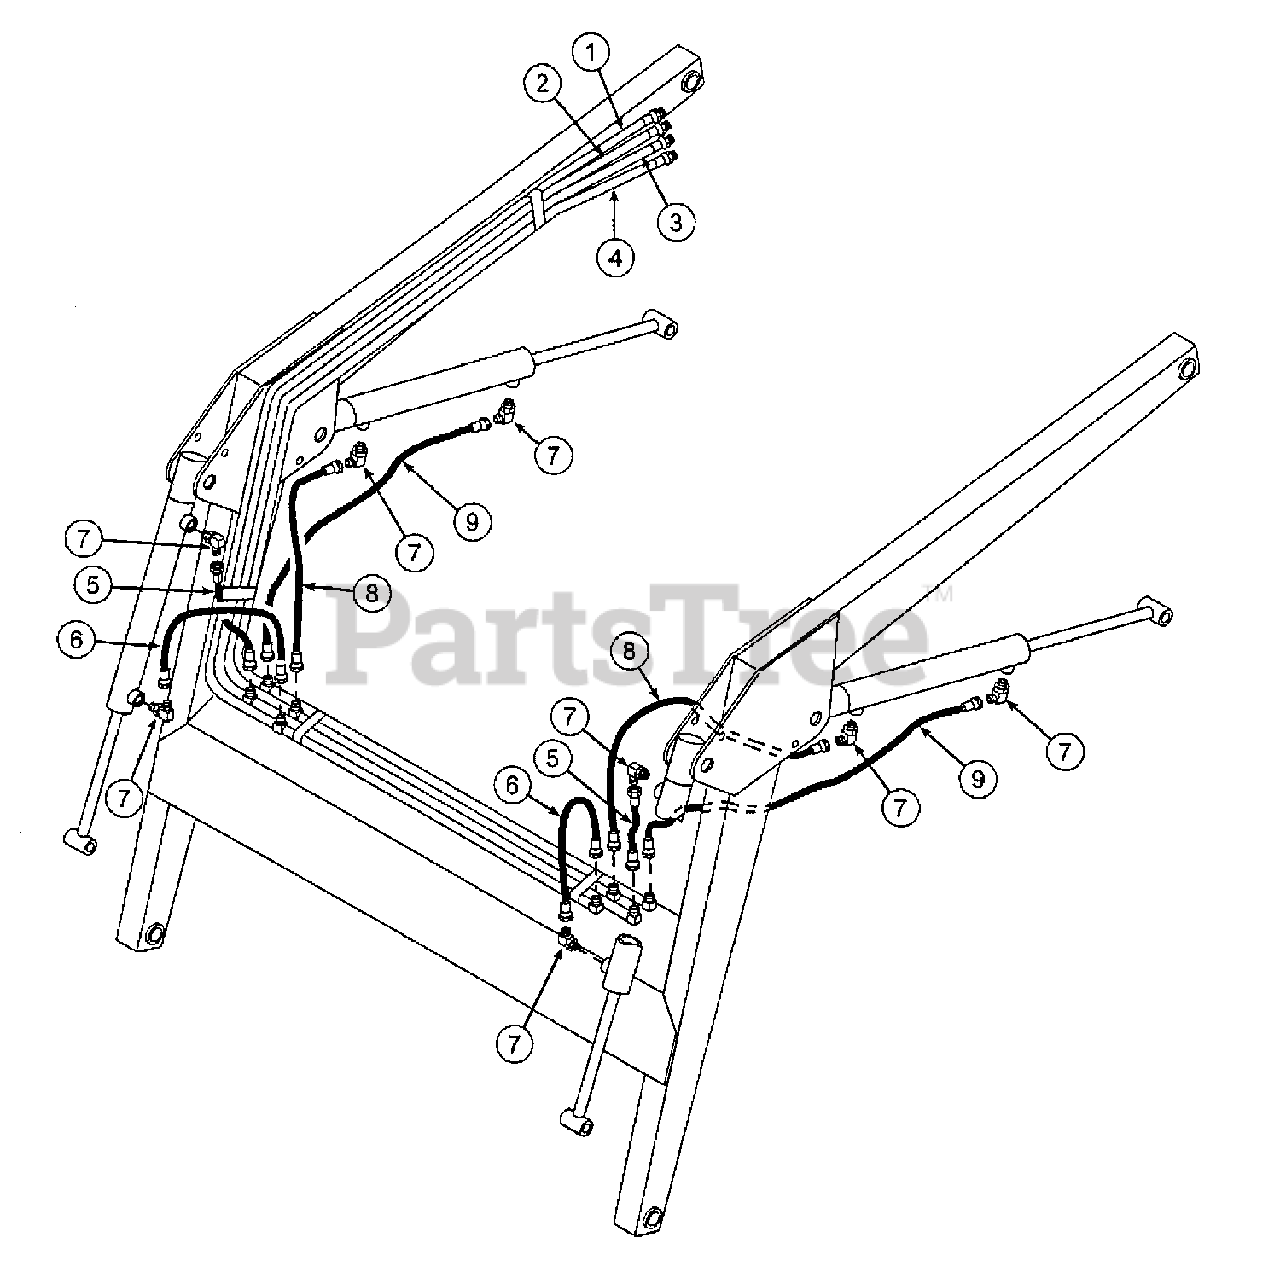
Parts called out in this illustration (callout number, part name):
1	TUBE, Oil Line, (BCB)
2	TUBE, Oil Line, (BCR)
3	TUBE, Oil Line, (LCB)
4	TUBE, Oil Line, (LCB)
5	HOSE, 1/4 x 10-1/2
6	HOSE, 1/4 x 15
7	FITTING, Elbow, 9/16 x 9/16, 90 Degree
8	HOSE, 1/4 x 20
9	HOSE, 1/4 x 34
